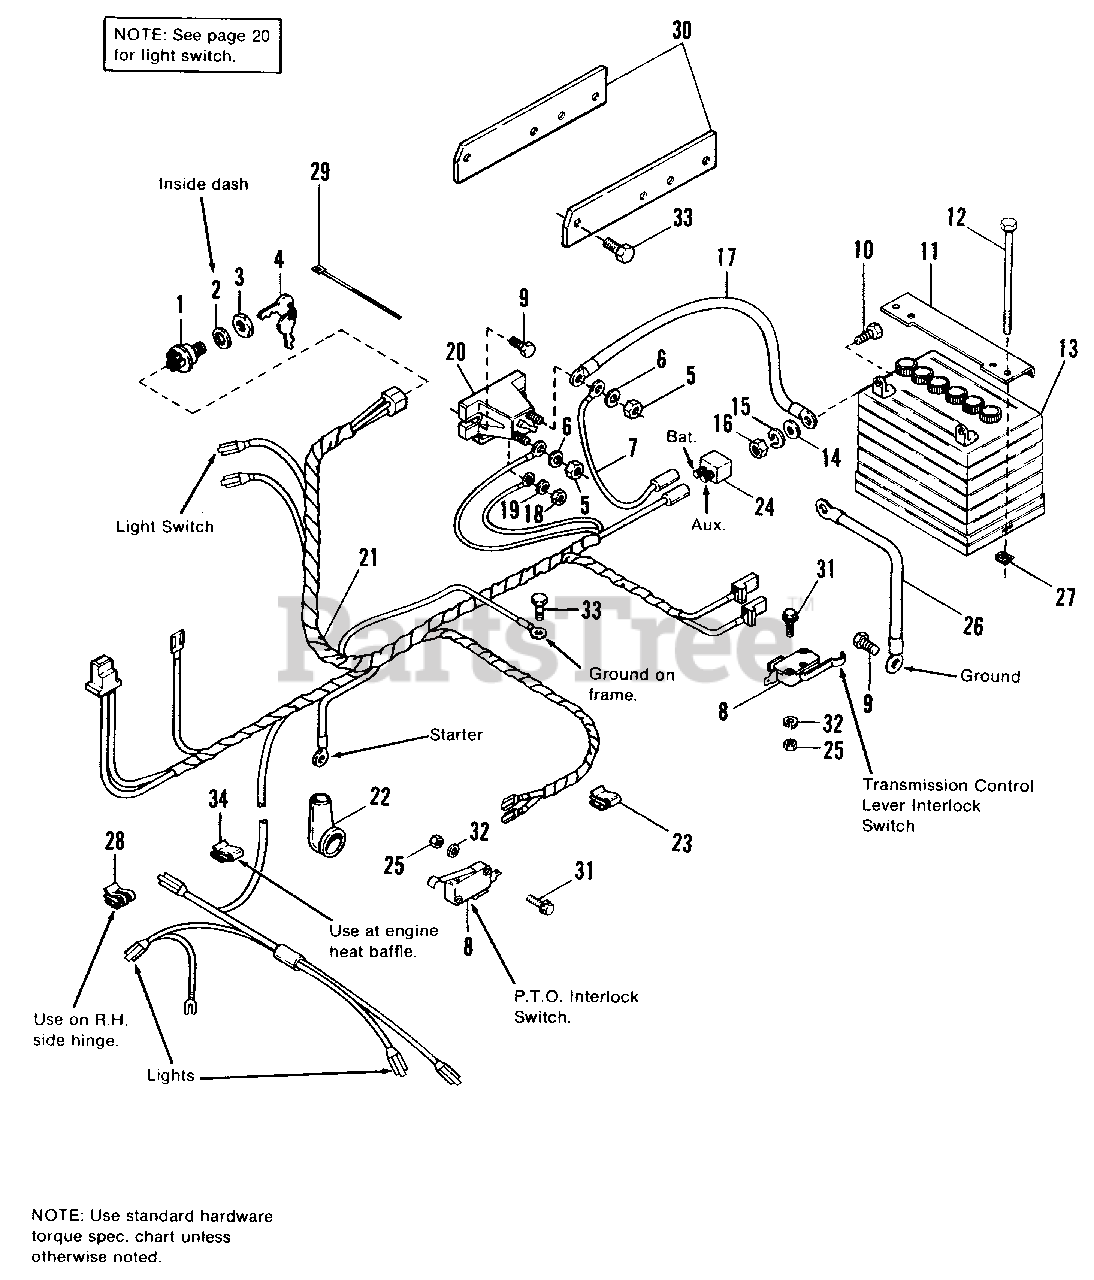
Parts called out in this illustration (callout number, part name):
1	SWITCH, Ignition
2	LOCKWASHER, Internal Tooth, 5/8
3	NUT, 5/8-32
4	KEYS, Set of 2
5	NUT, Hex, 5/16-18
6	LOCKWASHER, 5/16
8	SWITCH, Interlock
9	SCREW, Taptite, 1/4-20 x 5/8
10	CAPSCREW, Hex 1/4-20 x 3/4
11	CLAMP, Battery
12	CAPSCREW, Hex, 1/4-20 x 7-1/2
13	BATTERY SERVICE KIT, 39 Amp.
14	WASHER, 1/4
15	LOCKWASHER, 1/4
16	NUT, Hex, 1/4-20
18	NUT, Hex, #10-32
19	LOCKWASHER, Ext. #10
20	SOLENOID
21	HARNESS, Wiring
22	COVER, Terminal
23	CLIP, Speed
24	CIRCUIT BREAKER
25	NUT, Hex, #5-40
27	NUT, Retainer, 1/4-20
28	WIRE CLIP
29	TIE, Self-Locking
30	BRACE, Shift Panel
31	SCREW, Rd. Hd., Phil #5-40 x 3/4
32	LOCKWASHER, #5
33	SCREW, Taptite, 1/4-20 x 3/8
34	WIRE CLIP
